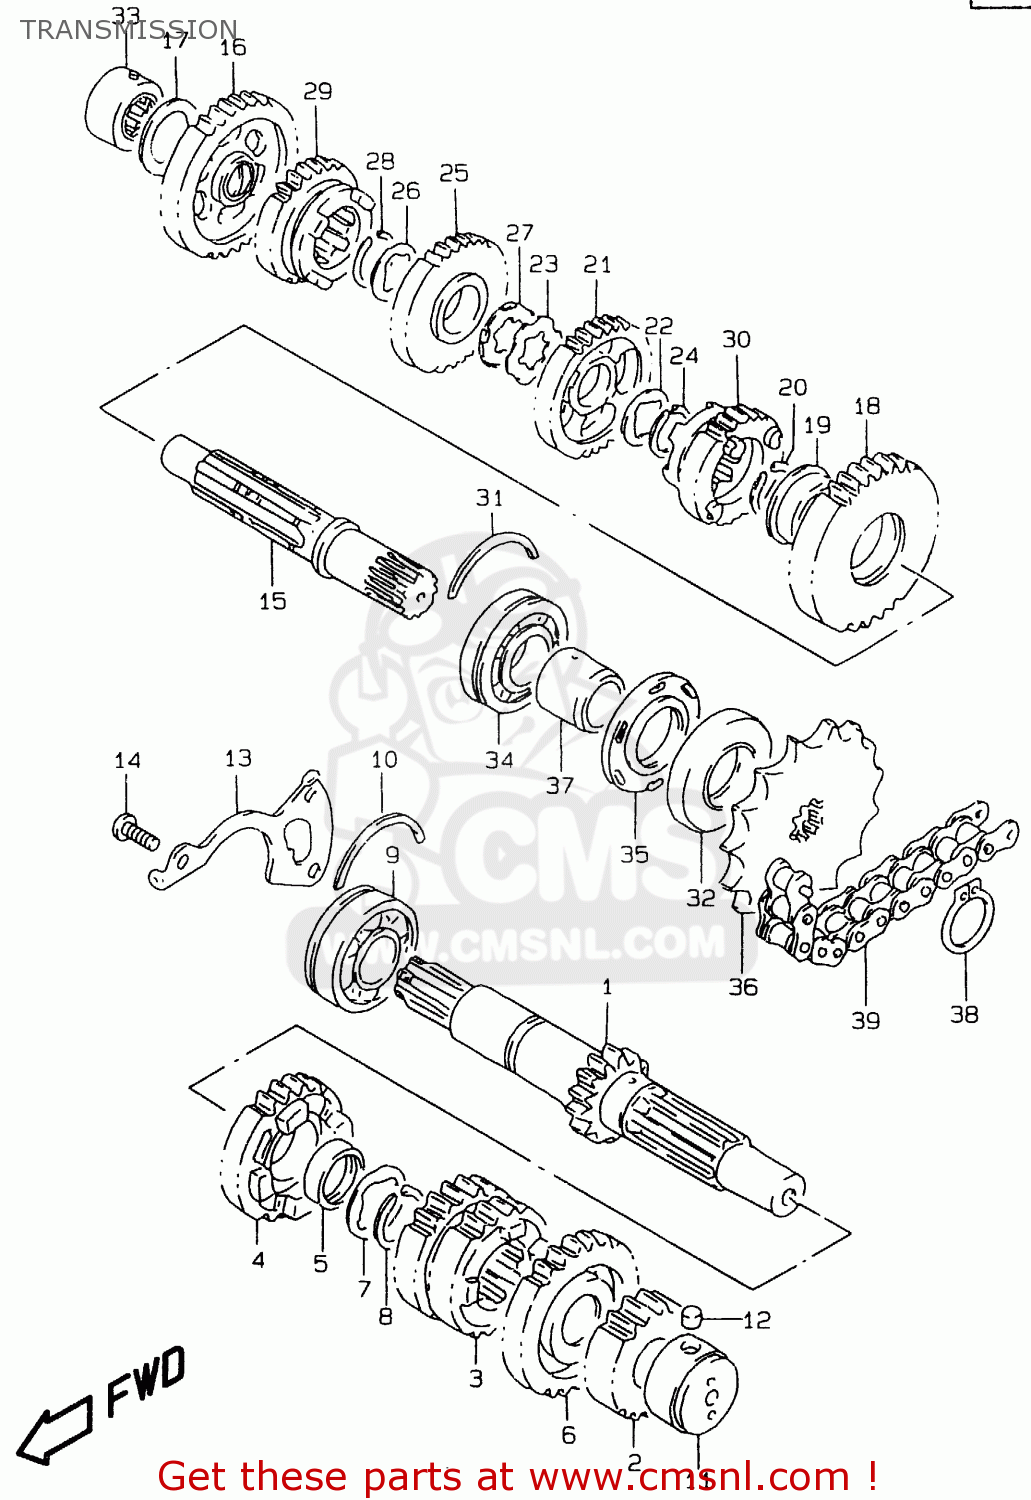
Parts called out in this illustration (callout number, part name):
1	SHAFT,COUNTER
2	GEAR,2ND DRIVE(NT:18)
3	GEAR,THIRD DRIVE
4	GEAR,FIFTH DRIVE (NT:26)
5	BUSHING 25X29X10
6	GEAR,6TH DRIVE
7	WASHER
8	CIRCLIP
9	BEARING(25X62X17)
10	C RING
11	BEARING(20X34X20)
12	PIN
13	PLATE,COUNTERSHAFT BEARING
14	SCREW ,6X16
15	SHAFT,DRIVE
16	GEAR,1ST DRIVEN
17	WASHER
18	GEAR,SECOND DRIVEN
19	BUSHING
20	CIRCLIP
21	GEAR,3RD DRIVEN
22	WASHER,LOCK
23	WASHER,LOCK
24	CIRCLIP
25	GEAR,4TH DRIVEN
26	WASHER,LOCK
27	WASHER
28	CIRCLIP
29	GEAR,5TH DRIVEN(NT:25)
30	GEAR,SIXTH DRIVEN
31	C RING
32	SEAL,OIL(32X62X7)
33	BEARING(20X34X17)
34	BEARING(25X62X17)
35	SEAL,OIL(32X62X5.5)
36	SPROCKET,ENGINE(16T)
37	SPACER,ENGINE SPROCKET
38	CIRCLIP
39	CHAIN(DID520VM,110L)
